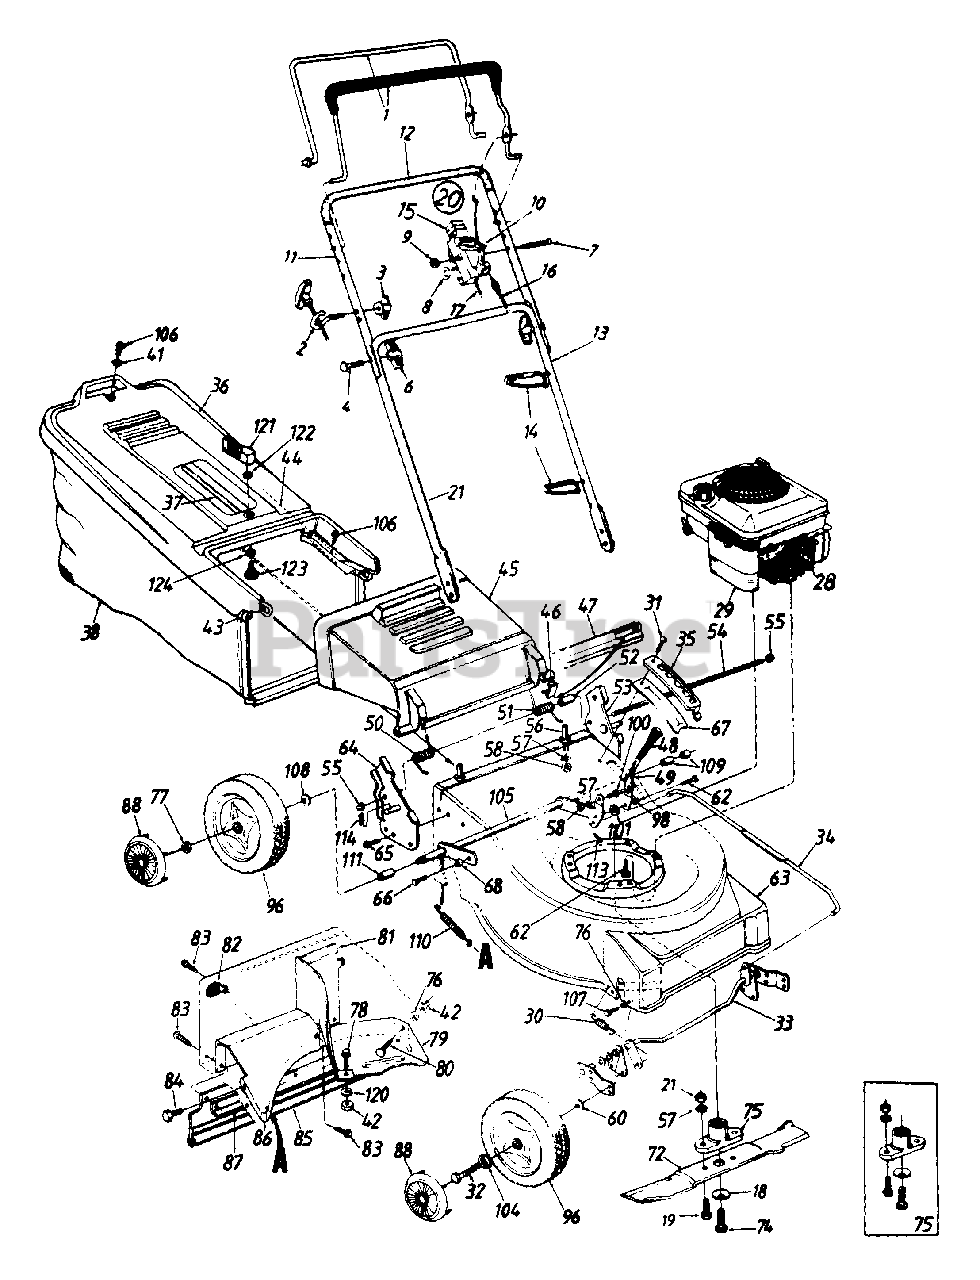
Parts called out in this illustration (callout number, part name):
2	Rope Guide
3	Wing Nut 1/4-20 Thd.
4	Curved Hd. Bolt 5/16-18 x 2" Lg.
6	2" Lg. Hand Knob
7	Oval C-Sunk Mach. Scr.
8	Spr. Wash..66" I.D
9	Hex L-Nut 1/4-20 Thd.
10	Throttle Lever
14	Cable Tie
15	Throttle Body
16	Control Cable
17	Throttle Control Wire - 55"
18	Bell-Wash 46" ID
19	Hex Bolt 3/8-24 x 1" Lg.
20	Throttle Box Comp
28	Spark Plug Boot
29	Engine
30	Extension spring 2.39" Lg
31	Torx Hd. AB-Tap Scr. 1/4"- 62" Lg.
32	Axle Bolt
34	Height Adj. Connecting Rod
35	Height Adjustment Plate
36	Hardtop Bag Cover
37	Hardtop Handle
38	Grass Bag
41	Fl-Wash..281" I.D. x .62" O.D.
42	Hex Nut 1/4-20 Thd.
44	Rear Catcher Frame
45	Chute Deflector
46	Deflector Plug
47	Seal - Extrusion
49	Spring Lever
50	Torsion spring - R.H.
51	Torsion spring - L.H.
52	Spacer .255" I.D.
53	Handle Brkt Ass'y - L.H.
54	Hinge Pin 17.75" Lg.
55	Cap Speed Nut
56	Shld. Pin 3/8-24 x 1.43" Lg.
57	L-Wash 3/8" I.D.
58	Hex Jam Nut 3/8-24 Thd.
60	Bell-Wash 38" I.D. x 88" O.D.
62	Hex L-Wash Hd. Scr. 3/8-16 x 1" Lg.
63	21" Deck Ass'y
64	Handle Brkt Ass'y - R.H.
65	Hex L-Wash Hd AB-Tap Scr 1/4 x 62" Lg.
66	Hex Wash Hd. Tap Scr. 3/8-16 x 75" Lg.
67	Height Adjustment Support
68	Spacer 385" I.D.
72	21" Blade
74	Hex Bolt 7/16-20 x 1.5" Lg.
75	Blade Adapter Kit
76	L-Wash 1/4" I.D.
77	Hex Jam Nut 1/2-20 Thd.
78	Hex Bolt 1/4-20 x 85" Lg.
79	Rear Belt Baffle
80	Carr Bolt 1/4-20 x .50" Lg.
83	Torx Mach AB-Tap Scr 1/4" x .62" Lg.
84	Hex B-Tap Scr 1/4 x 38" Lg.
85	Rear Flap
96	Wheel Ass'y Comp
98	Shld Spacer 50" Dia.
100	Shld. Pin 3/8-24 x 1.43" Lg.
101	Fl-Wash .375" I.D. x 1.0"
104	Wave Wash .53" I.D x .78"
105	Rear Axle Ass'y
106	Hex L-Wash AB-Tap Scr 1/4 x .62" Lg.
107	Hex L-Wash MD AB-Tap Scr 1/4 x .38" Lg.
108	Fl-Wash .510" I.D x .75"
109	Spacer 526" I.D.
110	Extension spring 3.8" Lg.
111	Sleeve .526" I.D.
113	Cotter Pin 3/32" Dia. x 75"
114	Internal Cotter Pin 5/16" Dia.
120	Bell-Wash. 1/4" I.D.
121	Grass Catcher Locking Knob
122	Internal L-Wash 1/4" I.D.
123	Shld Bolt .342" Dia. x .268
124	Wave Washer 3/8" I.D.
